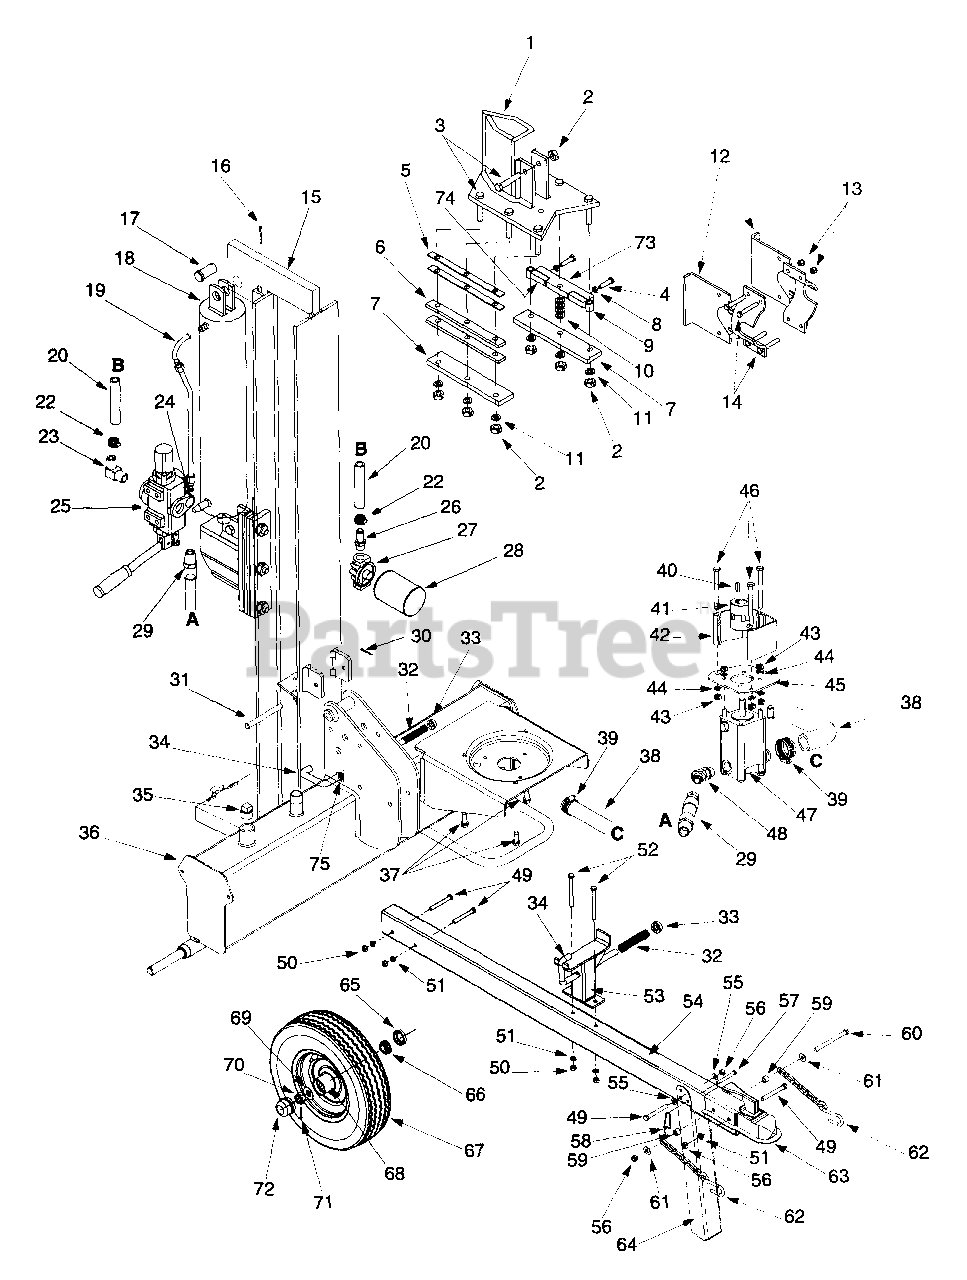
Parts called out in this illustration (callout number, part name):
2	Lock Nut 1/2-20
3	Hex Cap Screw 1/2-20 x 2.75
4	Hex Cap Screw 3/8-24 x 1.5
8	Hex Jam Nut 3/8-24
9	Spacer
10	Flat Washer .531 x .93 x .090
11	Lock Washer 1/2
14	Hex Cap Screw 3/8-16 x 2.0
17	Clevis Pin
20	Return Hose 3/4" I.D. x 44" Lg
22	Hose Clamp 5/8"
23	Return Elbow
24	90 deg. Solid Male Adapter
26	3/4" Hose Adapter
27	Filter Housing
28	Oil Filter
29	High Pressure Hydraulic Hose
30	Cotter Pin 1/8" Dia.
31	Hinge Pin 1/2 x 4.8" Lg.
32	Comp. Spring 4" Lg.
33	Push Cap
34	Locking Rod
35	Pipe Plug
38	Suction Hose
39	Hose Clamp
40	Sq.-Key 3/16" x .75"
41	Flexible Coupling
42	Coupling Shield
43	Hex Nut 5/16-24
44	L-Wash. 5/16" I D
46	Hex Screw 5/16-24 x 3 25
47	Gear Pump (11 GPM)
48	45 Degree Elbow
49	Hex Bolt 3/8-16 x 3" Lg
50	Hex Nut 3/8-16 Thd
51	L-Wash. 3/8" I.D.
52	Hex Bolt 3/8-16 x 4" Lg
55	Flat Washer 3/8
56	Hex L-Nut 3/8-16 Thd
57	Clevis Pin 5/16 x 2.5" Lg
58	Spring Pin
59	Spacer 3/8" I.D x .625" O.D.
60	Hex Bolt 3/8-16 x 4" Lg (Grd 5)
61	Fl-Wash. 3/8" I.D. x 87" O.D.
62	Chain - Tow Hitch
63	Hitch Coupler
66	Bearing Cone
67	Wheel Asm Comp - Gray
68	Bearing Cup
69	Fl-Wash. .76" I.D. x1.5" O.D
70	Slotted Nut 3/4-16 Thd
71	Cotter Pin 5/32" Dia. x 1-1/4" Lg.
72	Hub Cap
75	Flat Washer .635 ID x .93 OD
